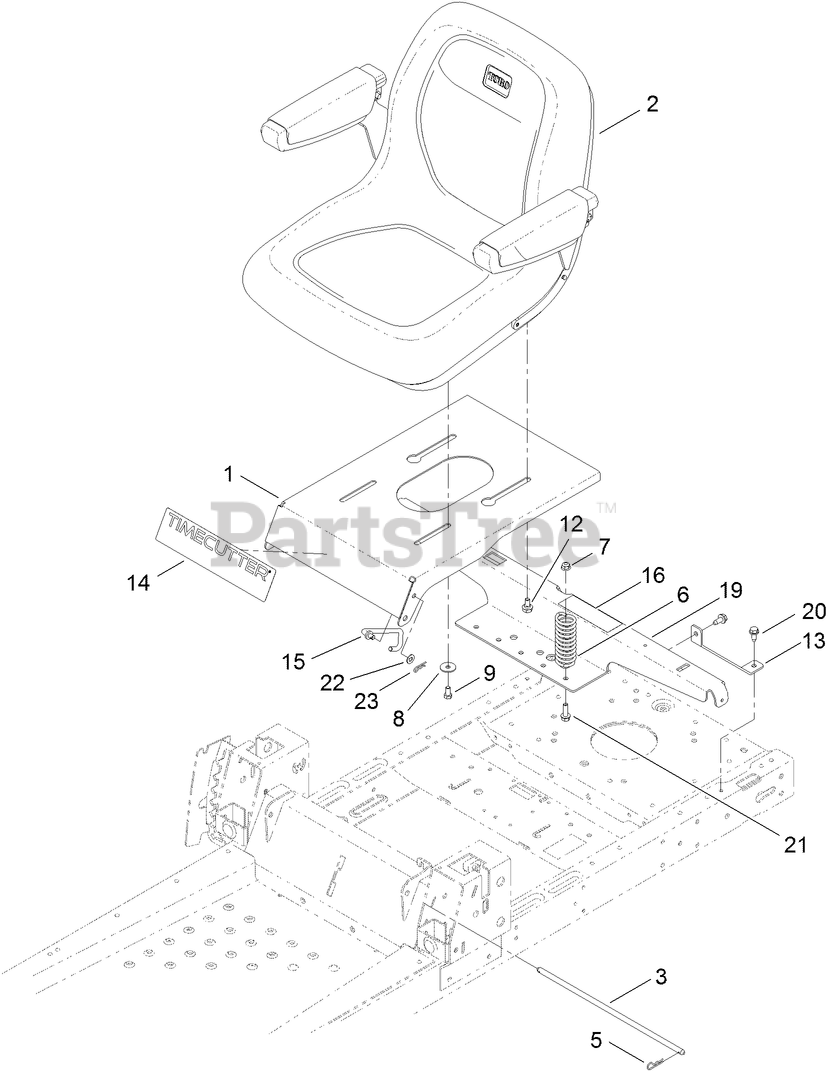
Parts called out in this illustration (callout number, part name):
2	SEAT-18 INCH
3	ROD-PIVOT, NARROW
5	PIN-COTTER
6	SPRING-COMPRESSION
7	NUT-HF, NI
8	WASHER-PIVOT
9	SCREW-HH
12	BOLT-SHOULDER,HFH
13	SUPPORT-TANK, REAR
14	DECAL-TIMECUTTER
15	STOP-SEAT
16	DECAL-SERVICE, CE
19	SUPPORT-POD
20	SCREW-HWHTF
21	SCREW-HHF
22	WASHER-PLAIN
